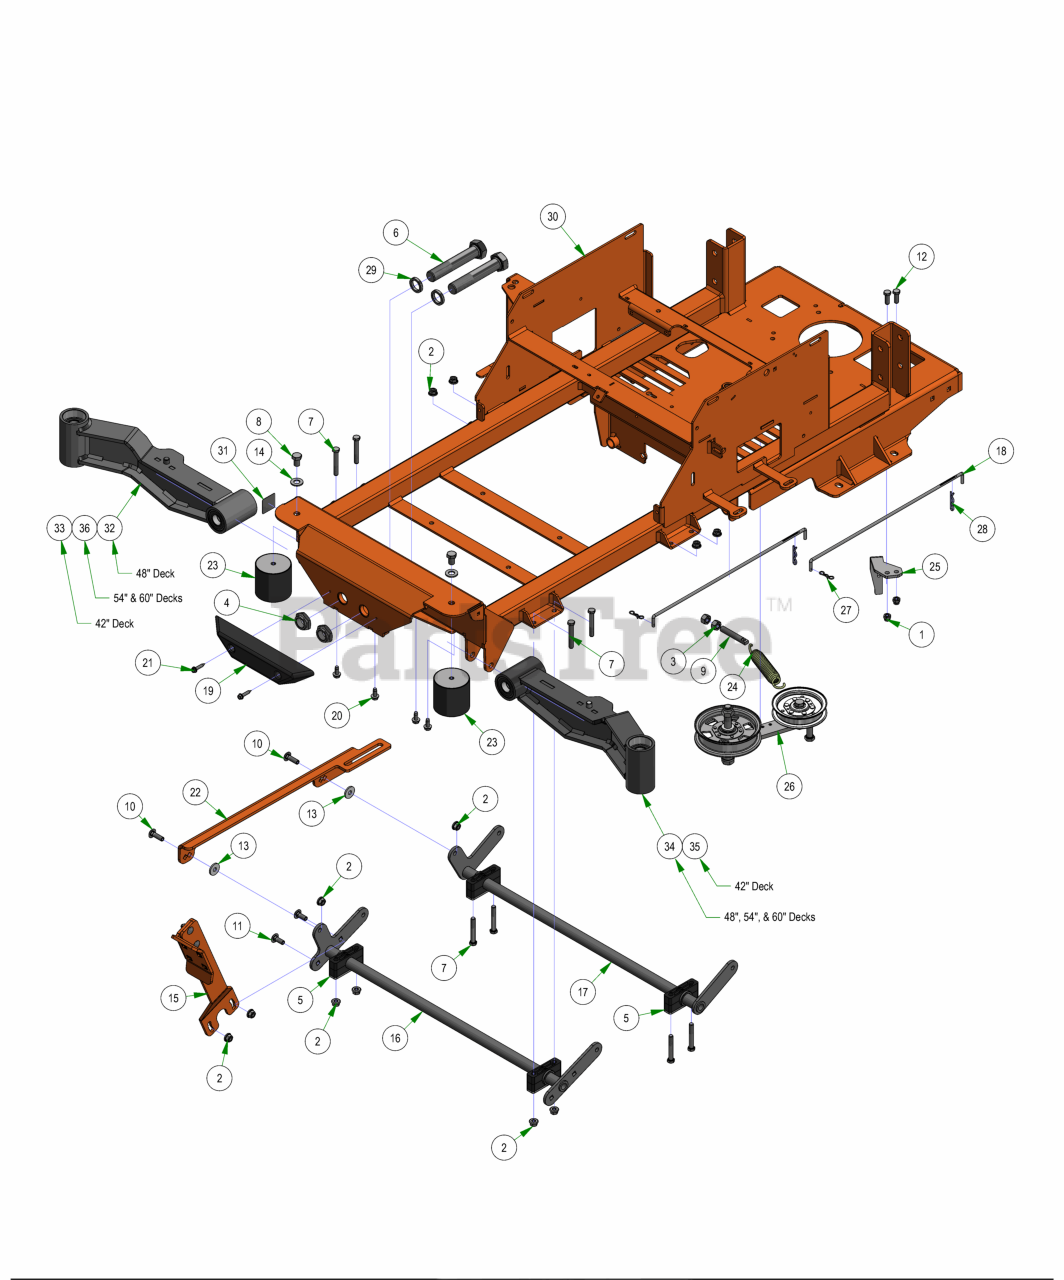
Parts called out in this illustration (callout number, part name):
1	3/8-16 NYLON INSERT LOCKNUT ZINC
2	3/8-16 NYLON INSERT FLANGE LOCKNUT (GR.F) ZINC
3	1/2-13 HEX NUT ZINC
4	1"-14 NYLON INSERT JAM LOCKNUT ZINC
5	Pillow Block Kit
6	1"-14 X 5-1/2 HEX CAP SCREW (GR.8) ZINC YELLOW
7	3/8-16 X 2-1/2 HEX CAP SCREW (GR.5) ZINC
8	1/2-13 X 3/4 HEX CAP SCREW (GR.5) ZINC
9	All Thread
10	3/8-16 X 1-1/4 CARRIAGE BOLT ZINC
11	3/8-16 X 1 CARRIAGE BOLT (GR.5) ZINC
12	3/8-16 X 1 GR 5 Hex Bolts Zinc
13	.390 ID X 1.12 OD X .125 THK FLAT WASHER NYLON
14	1/2 SAE FLAT WASHER (1-1/16" OD) GR.8 ZINC YELLOW
15	Foot Pedal Assembly
16	Actuator Bar Front- 2017 MZ/ZT
17	Actuator Bar Rear- 2017 MZ/ZT
18	Neutral Rod
19	Bumper EZT
20	5/16-18 X 3/4 HEX WASHER SLOT (F) TCS ZINC
21	1/4-14 X 1-1/4 HEX WASHER UNSLOT TEK/3 ZINC
22	2017 MZ/ZT Actuator Linkage
23	Vibration Mount- Red Dot
24	Deck Idler Spring
25	2025 ZT Clutch Bracket
26	Maverick Pump Idler
28	Neutral Rod Clip
29	1.02 ID X 1.38 OD X .250 THK SPACER ZINC
30	2025 Maverick Frame
31	Independetly Articulating Front Suspension Arms Patent Decal
32	2021 Maverick RH Short Front Suspension Arm Assy (48")
33	2022 Maverick RH Front Suspension Arm Assy (42'')
34	2021 Maverick LH Front Suspension Arm Assy (48", 54" & 60")
35	2022 Maverick LH Front Suspension Arm Assy (42'')
36	2021 Maverick RH Long Front Suspension Arm Assy (54" & 60")
